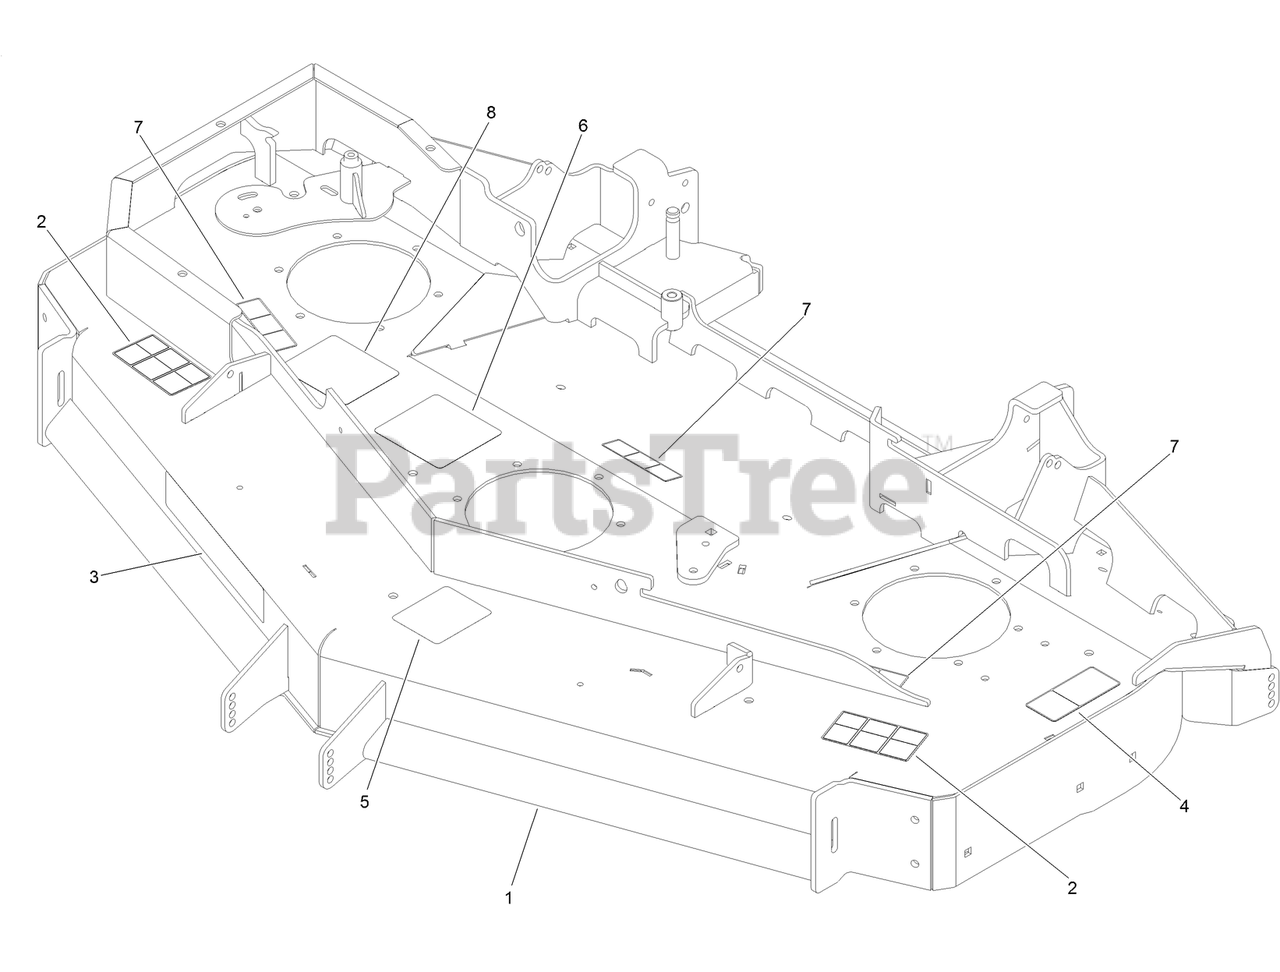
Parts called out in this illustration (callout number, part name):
1	DECK DECAL ASM
2	DECAL-DANGER
4	DECAL-TORQUE, BLADE BOLT
5	DECAL-ROLLER, ANTI-SCALP
6	DECAL-ROUTING, DECK BELT
7	DECAL-COVER, MISSING
8	DECAL-SPINDLE, COUNTER ROTATING
